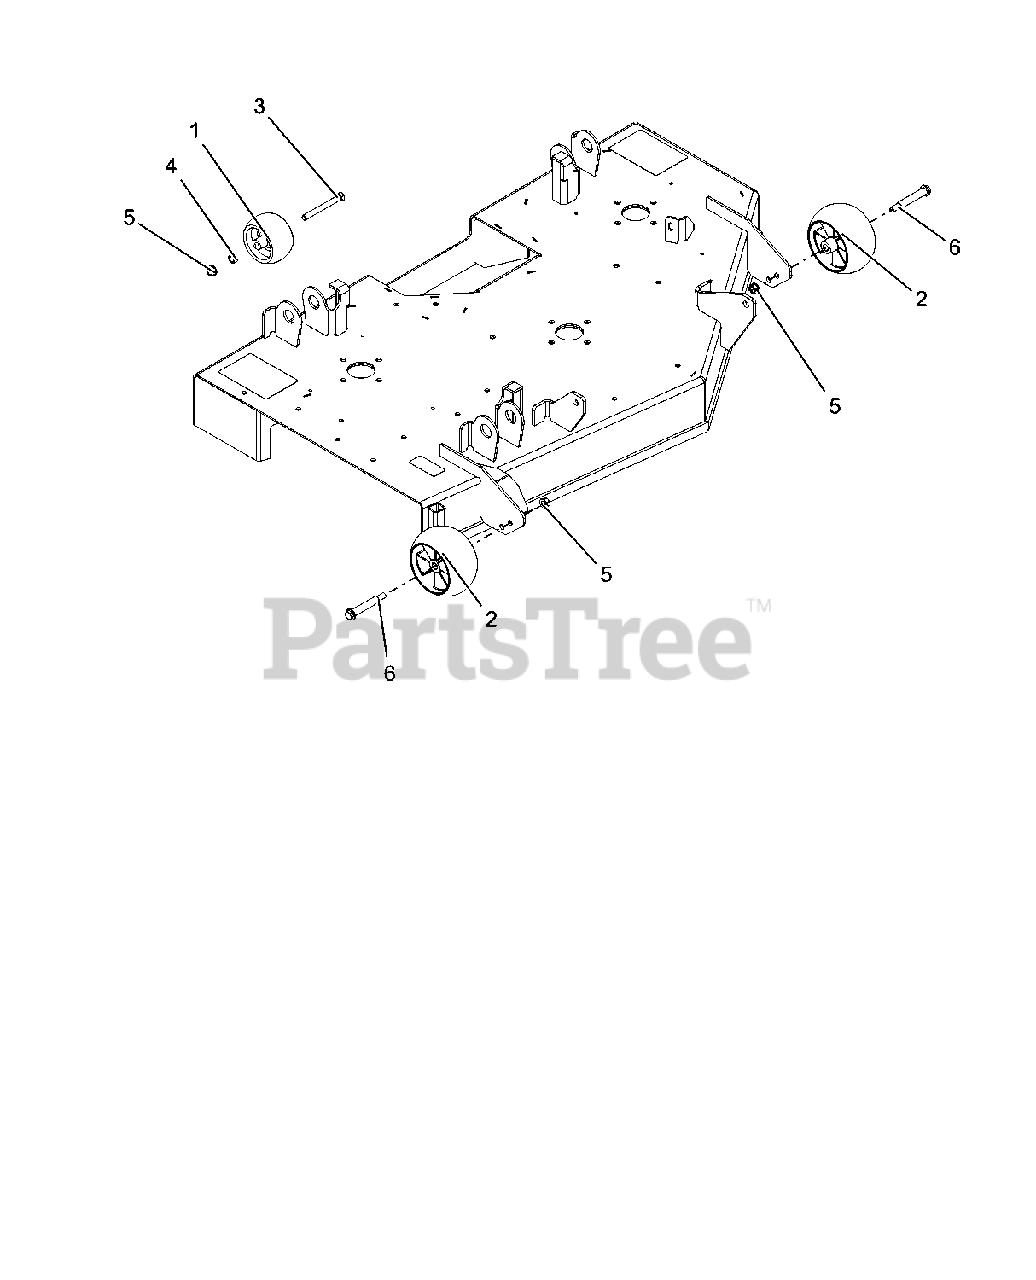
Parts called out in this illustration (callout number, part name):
2	ANTI-SCALP WHEEL - 5X OS
3	@BLT-HEX .38-16X3.50 GR5 YWZC
4	@NUT-HEX .38-16 YWZC
5	@NUT-LK-TOP-FLG .38-16 YWZC
6	BLT-SHLDR .38-16X2.50 HWH G5
